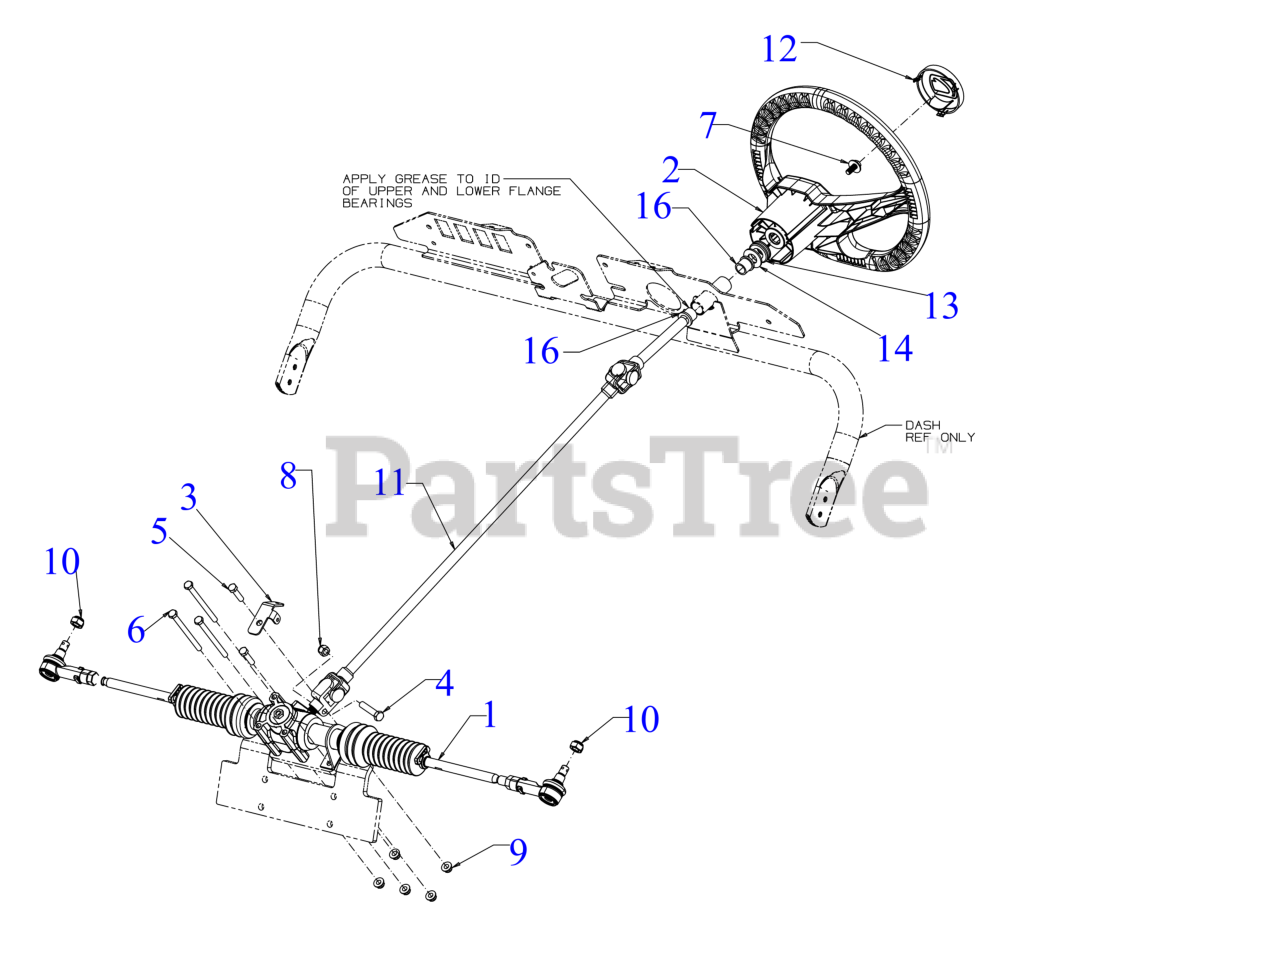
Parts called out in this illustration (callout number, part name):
1	STEERING GEARBOX ASSEMBLY
2	STEERING WHEEL
3	FRONT CABLE MOUNTING BRACKET
4	HEX SCREW 3/8-16 x 1.75 GR5
5	SCREW 5/16-18 x 1.25 GR5
6	SCREW 5/16-18 x 4.00 GR5
7	SCREW 5/16-24 x .85 GR5
8	HEX NUT INS L-3/8-16
9	FLANGE LOCK NUT 5/16-18
11	STEERING SHAFT
12	STEERING WHEEL CAP
13	RUBBER GROMMET
14	FLAT WASHER .656 x 1.312 x .097
16	FLANGE BEARING
